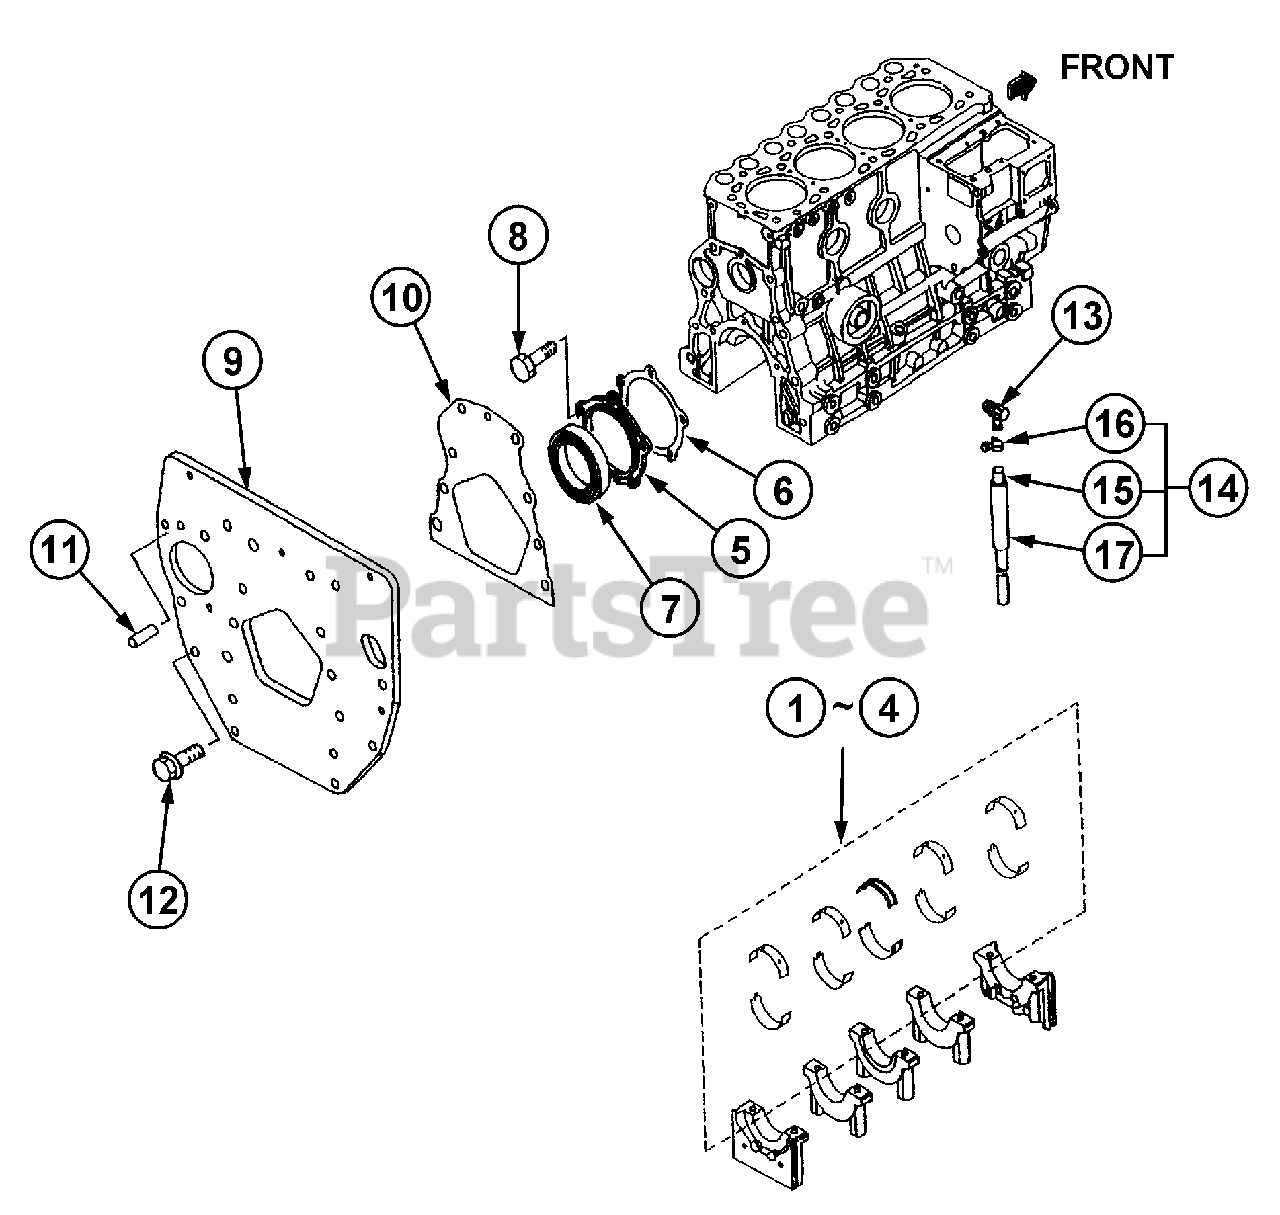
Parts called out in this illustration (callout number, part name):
1	Bearing Set (STD)
2	Bearing Set (U.S. 0.25)
3	Bearing Set (U.S. 0.50)
4	Bearing Set (U.S. 0.75)
5	Case, Oil Seal
12	Bolt, Flange
13	Joint, Water Drain
14	Hose Assy, Water
15	Hose, Fuel
17	Hose, Rubber
